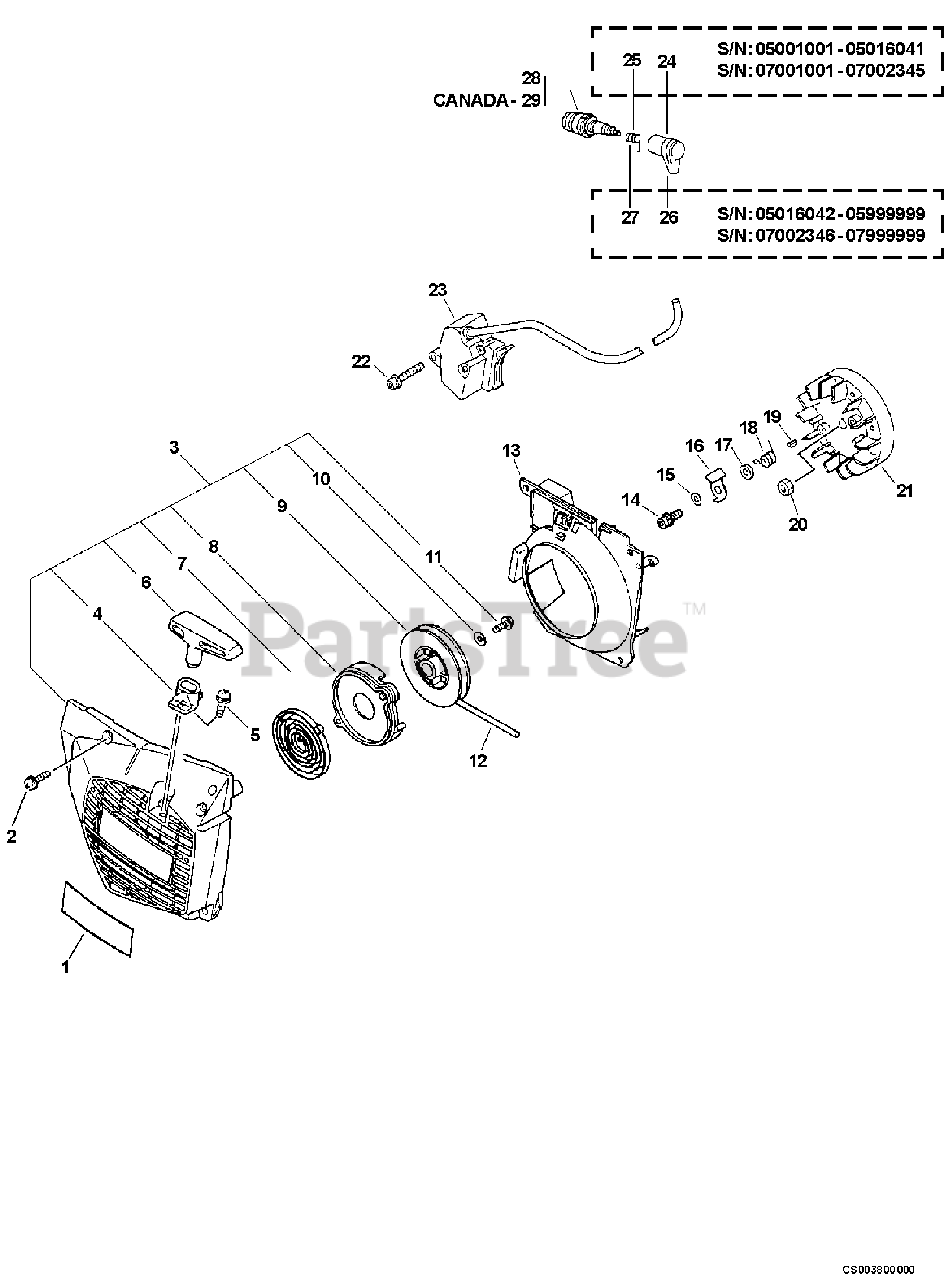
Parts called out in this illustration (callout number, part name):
1	LABEL - ECHO
2	SCREW - 5X18
3	STARTER ASSY
4	GUIDE, ROPE
5	SCREW - 3X14
6	GRIP, STARTER
7	SPRING, REWIND
8	PLATE, STARTER
9	REEL, ROPE
10	WASHER - 5
11	SCREW - 5X12
12	ROPE, STARTER - 3.5X960
13	COVER, FAN
14	SCREW - 5X14
15	WASHER - 5
16	PAWL, STARTER
18	SPRING, RETURN
20	NUT - 8 -- FLANGE
21	FLYWHEEL
22	SCREW - 4X30
23	COIL, IGNITION
24	CAP, SPARK PLUG
25	TERMINAL, SPARK PLUG CAP
26	CAP, SPARK PLUG
27	TERMINAL, SPARK PLUG CAP
28	SPARK PLUG -- BPM-7A
29	SPARK PLUG -- BPMR-8Y
